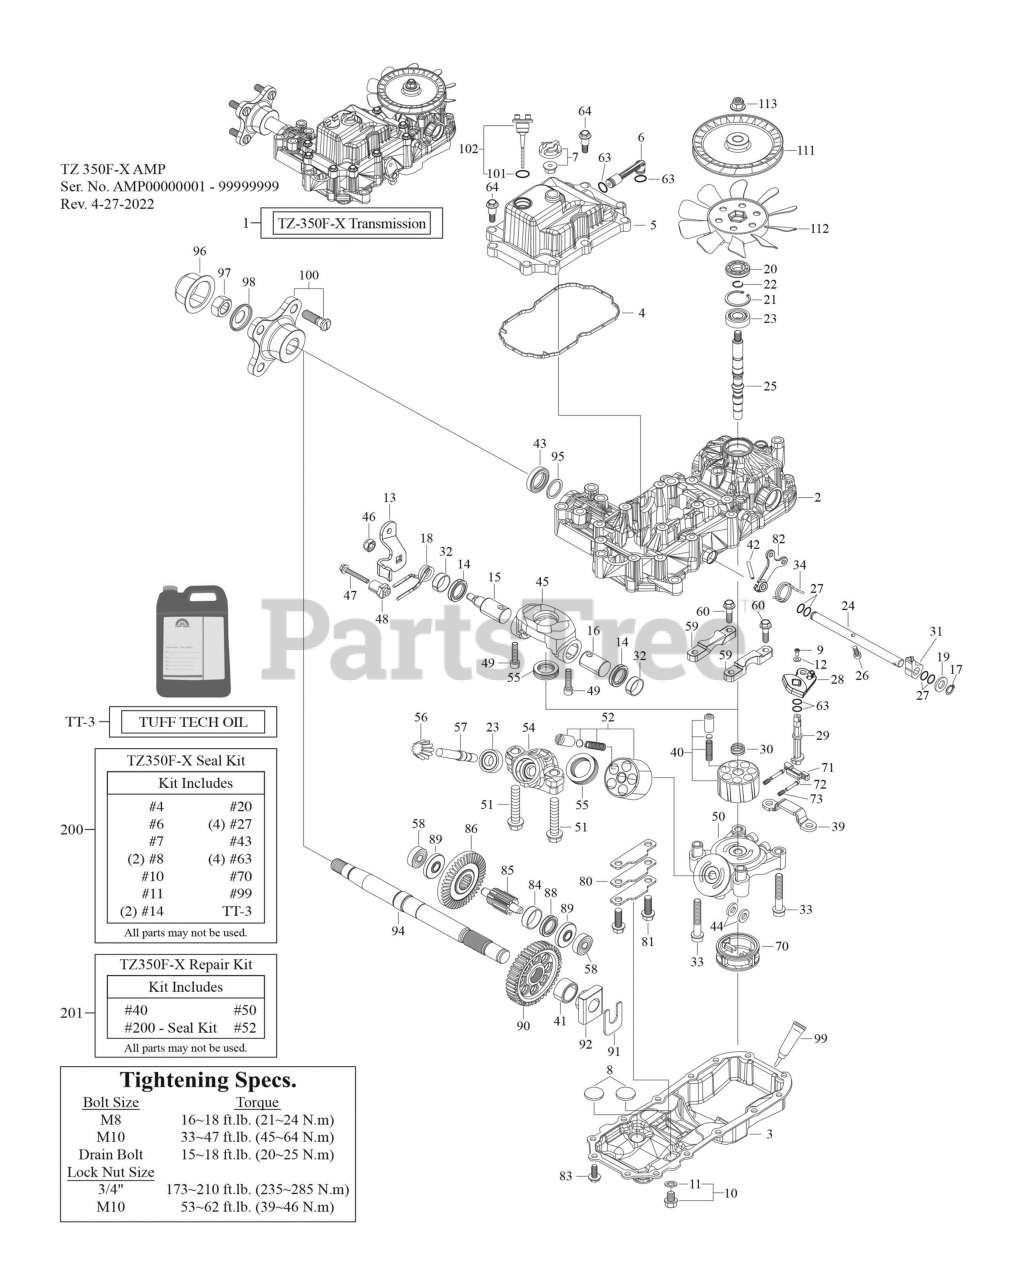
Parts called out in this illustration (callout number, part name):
1	HYDRO TRANSMISSION (LH)
2	UPPER HOUSING X
3	LOWER HOUSING
6	BYPASS PIPING
7	VALVE ASSEMBLY-VENT
10	DRAIN BOLT KIT
11	WASHER-SEAL DRAIN BOLT
12	WASHER 4.5X10X1
13	CONTROL LEVER X
15	CONTROL SHAFT
16	CONTROL SHAFT SHORT
18	TORSION SPRING
19	FLAT WASHER 12
20	SEAL-OIL 15X35X07
23	BALL BEARING
26	SOCKET BOLT 6X16
30	SPRING-CYL BLOCK
31	BRAKE FORK 20 CR
32	CONTROL BUSH LFB2510
33	HEX BOLT M10X65
34	SPRING, BRAKE XA
39	CHECK STOPPER PFG
40	CYLINDER BLOCK KIT
42	SPRING PIN 5 x 3
43	SEAL TC284008
50	CENTER CASE
52	BLOCK KIT-PISTON & MOTOR
54	MOTOR HOUSING
55	THRUST BEARING
58	BEARING 6201 CN
59	REDUCTION PLATE
60	FLANGE BOLT 8X30
64	TAPPING BOLT 8X30
73	BYPASS SPRING
83	TAP SCREWPING
84	FINAL PINION COLLAR
85	FINAL PINION SHAFT
86	REDUCTION GEAR
88	REDUCTION COLLAR
89	WASHER 14.1X30X3.5
97	LOCK NUT 3/4-16
98	FLANGE SPACER
113	NUT-LOCK PMP SHAFT
200	SEAL KIT (INCLUDES OIL)
201	REPAIR KIT (INCLUDES OIL)
202	OIL CHANGE KIT (TZ-350)
TT-3	TUFF TECH OIL 3 LITER BOTTLE
